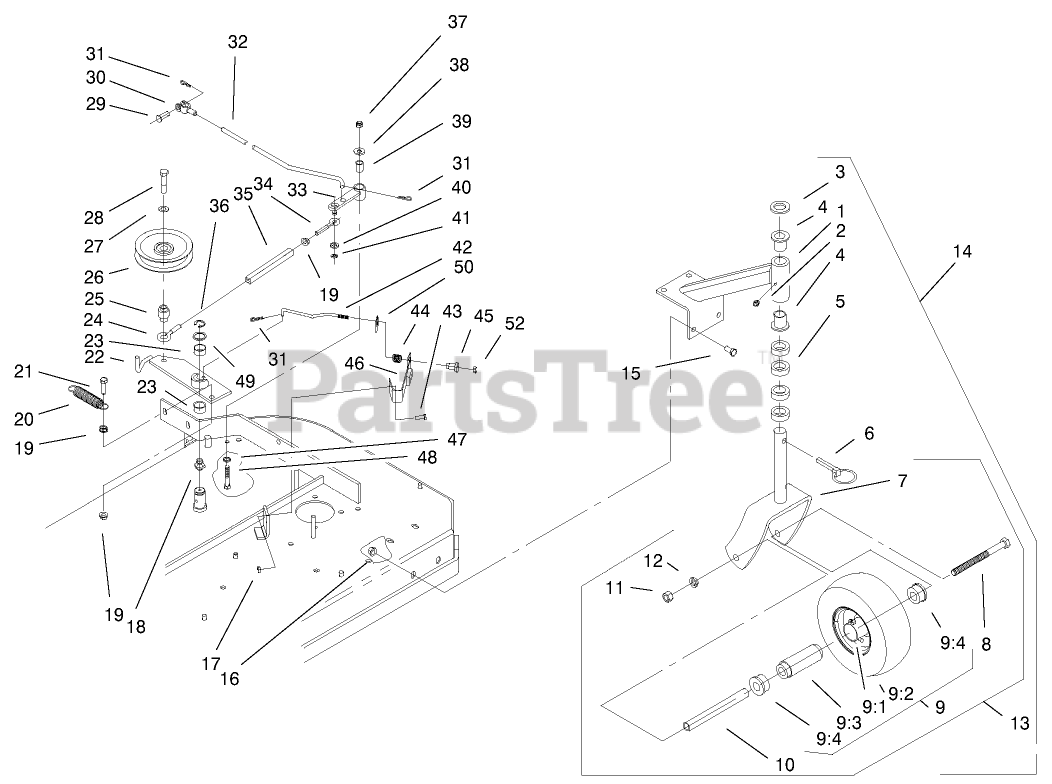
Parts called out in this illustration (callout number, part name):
1	Support-Caster
2	FITTING-GREASE
3	Washer
4	Bearing-Flanged
5	Spacer
6	Pin
7	Fork
8	SCREW-HH
9	WHEEL AND TIRE ASM
9:1	Wheel Hub ASM
9:2	Tire
9:3	Bearing
9:4	Bushing
10	Spacer
11	NUT-HH
12	WASHER-LOCK
13	Caster Wheel ASM
14	Caster/Mount ASM
15	SCREW-HH
16	NUT-HHF, WHIZ
17	NUT-LOCK, NI
18	FITTING-GREASE
19	NUT-HF
20	Spring
21	SCREW-HH
22	Engagement Arm w/Bushings
23	Bearing-Sleeve
24	Eye Bolt
25	Bushing
26	Pulley-Idler
27	Washer
28	SCREW-HH
29	Pin-Clevis
30	Yoke
31	PIN-COTTER
32	Linkage-Assist Arm
33	Assist Arm ASM
34	Eye Bolt
35	Turnbuckle Body
36	RING-RETAINING, EXT
37	NUT-LOCK, NI
38	WASHER-FLAT
39	Tube-Pivot
40	WASHER-PLAIN
41	E-Ring
42	Rod-Brake
43	SCREW-HH
44	Spring-Compression
45	Spacer-Flanged
46	Pad/Spring ASM
47	Washer-Lock
48	SCREW-HH
49	Spindle Washer
50	Ring-Push On
52	NUT-LOCK, NI
